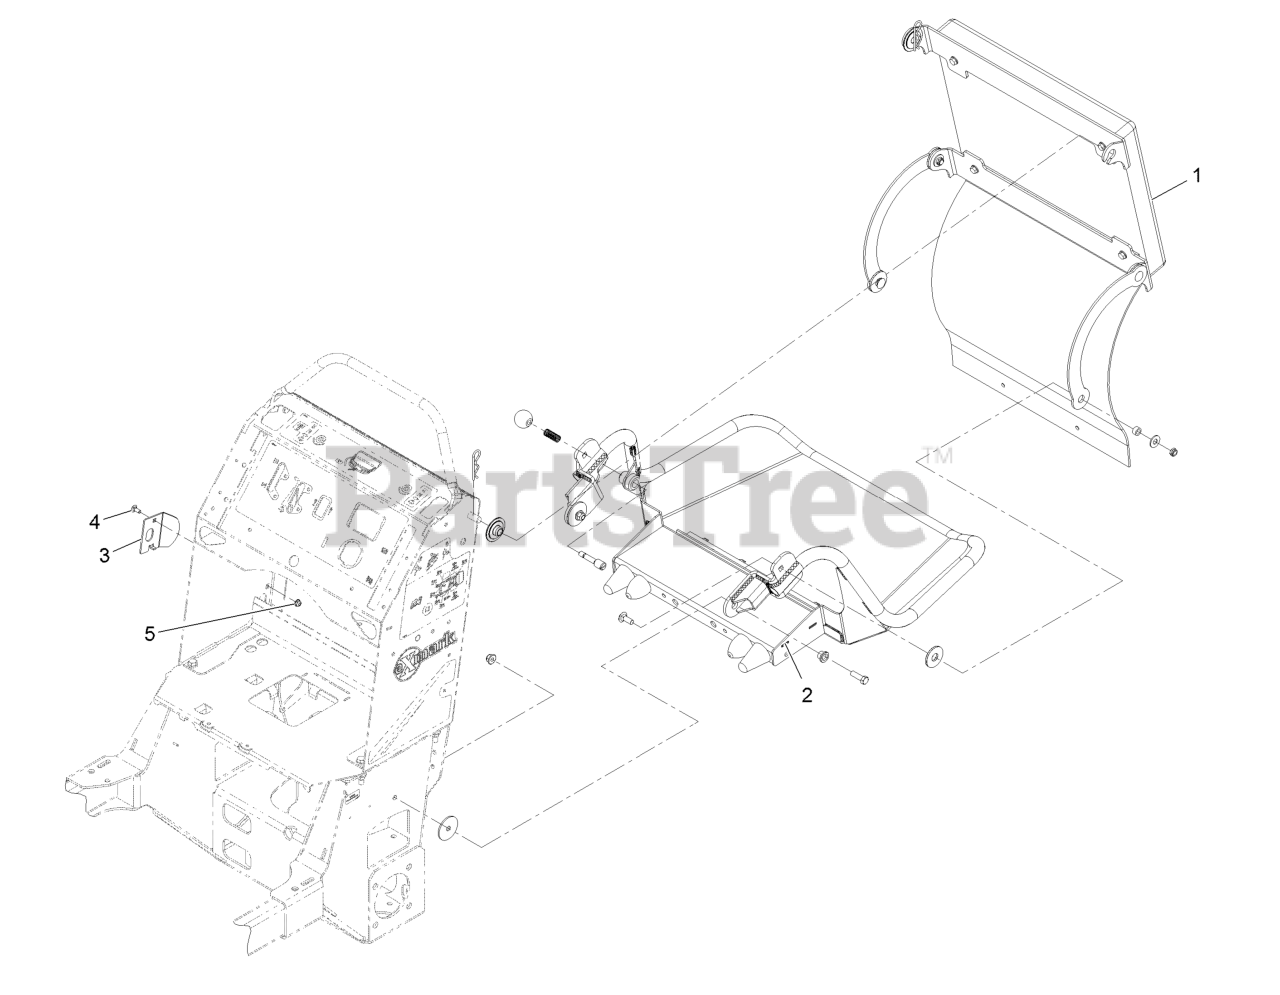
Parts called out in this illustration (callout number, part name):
1	ASM, Cushion
2	Platform ASM
3	Plate-Striker
4	Bolt-Carriage 1/4-20 X 5/8
5	Nut-Nyloc 1/4-20 Flg
